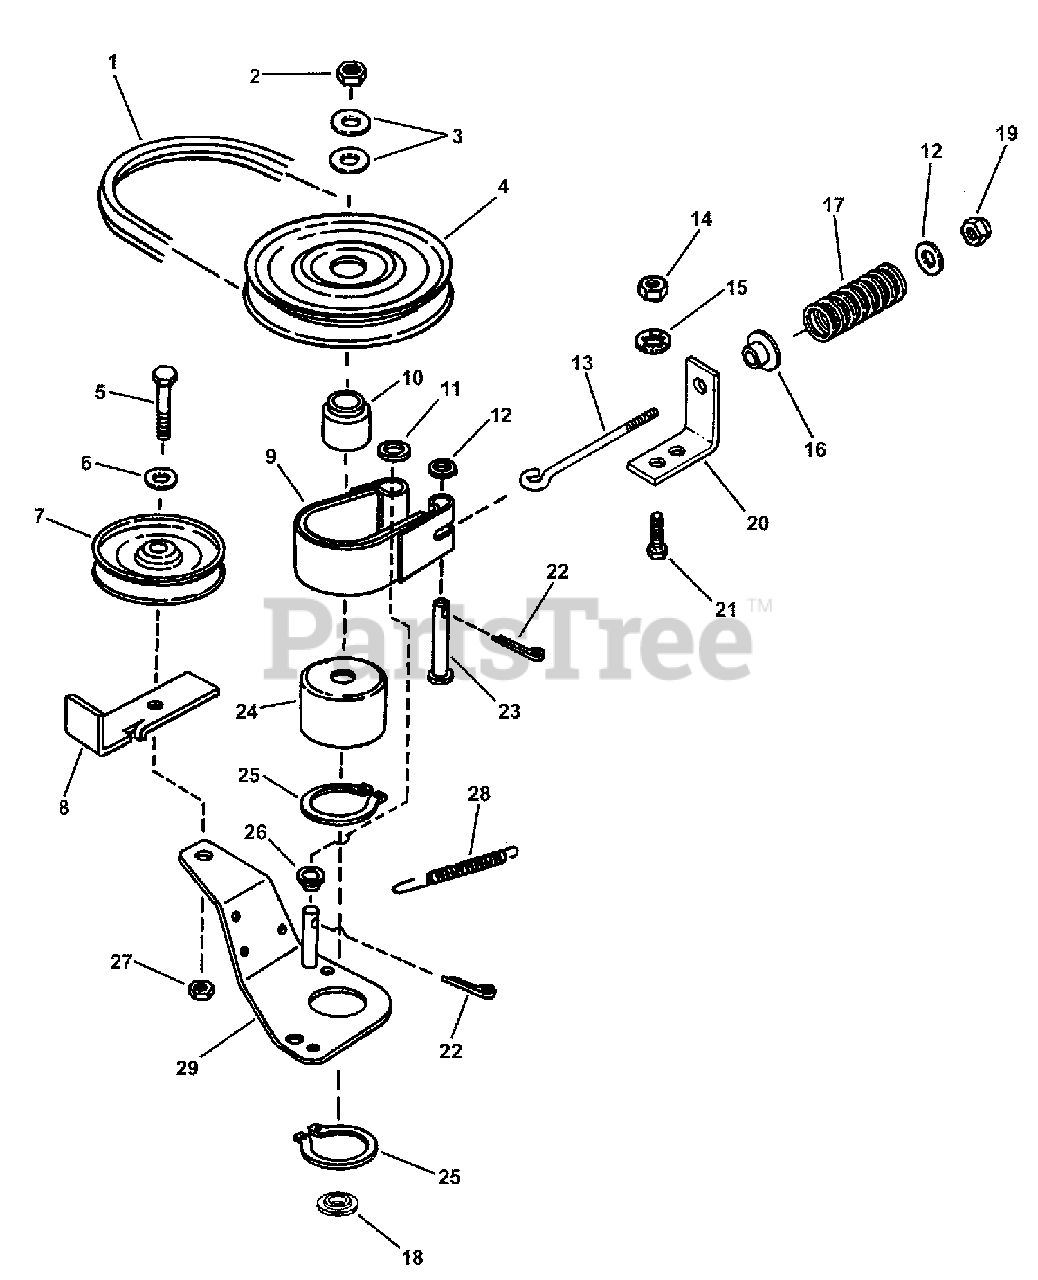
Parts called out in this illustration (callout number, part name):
1	BELT, Engine Drive
2	NUT, 3/4-16 Hex Jam GR 8
3	WASHER, 49/64 x 1-1/2" Flat
4	PULLEY, Deck Spindle
5	SCREW, 3/8-24 x 1-3/4" Hex Head Cap GR5
6	WASHER, 3/8" Flat
7	PULLEY, Idler
8	RESTRICTOR, Belt
9	BAND, Brake
10	HUB, Pulley
11	WASHER, 3/8" Flat
12	WASHER, 1/4" Flat
13	EYEBOLT, 1/4-20 x 4"
14	NUT, 5/16-24 Hex
15	WASHER, 5/16" Internal Tooth Lock
16	BUSHING, Flange
17	SPRING
18	WASHER, Spindle
19	NUT, 1/4-20 Hex Top Lock
20	ANCHOR
21	SCREW, 5/16-24 x 3/4" Hex Head Cap GR5
22	PIN, 3/32 x 3/4" Cotter
23	PIN, 1/4 x 1-5/8" Clevis
24	DRUM, Brake
25	RING, 2" External Retaining
26	SPACER
27	NUT, 3/8-24 Hex Nyloc
28	SPRING, Brake
29	ARM, Idler
